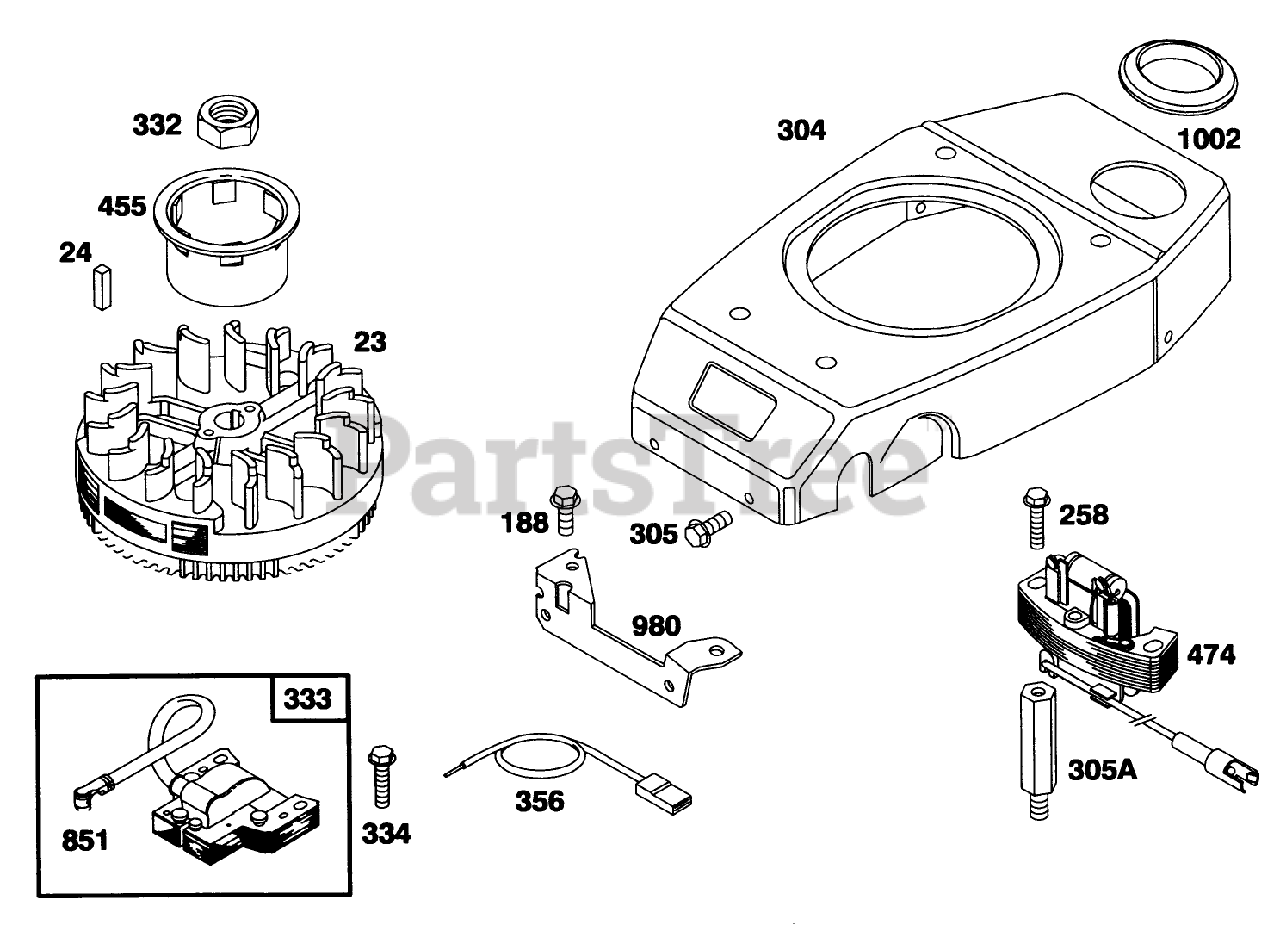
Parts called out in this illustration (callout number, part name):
23	FLYWHEEL - MAGNETO
24	KEY - FLYWHEEL
37	GUARD - FLYWHEEL
305	SCREW - HEX HEAD
332	NUT - HEXAGON
356	WIRE - GROUND
980	BRACKET-BLOWER HSG
